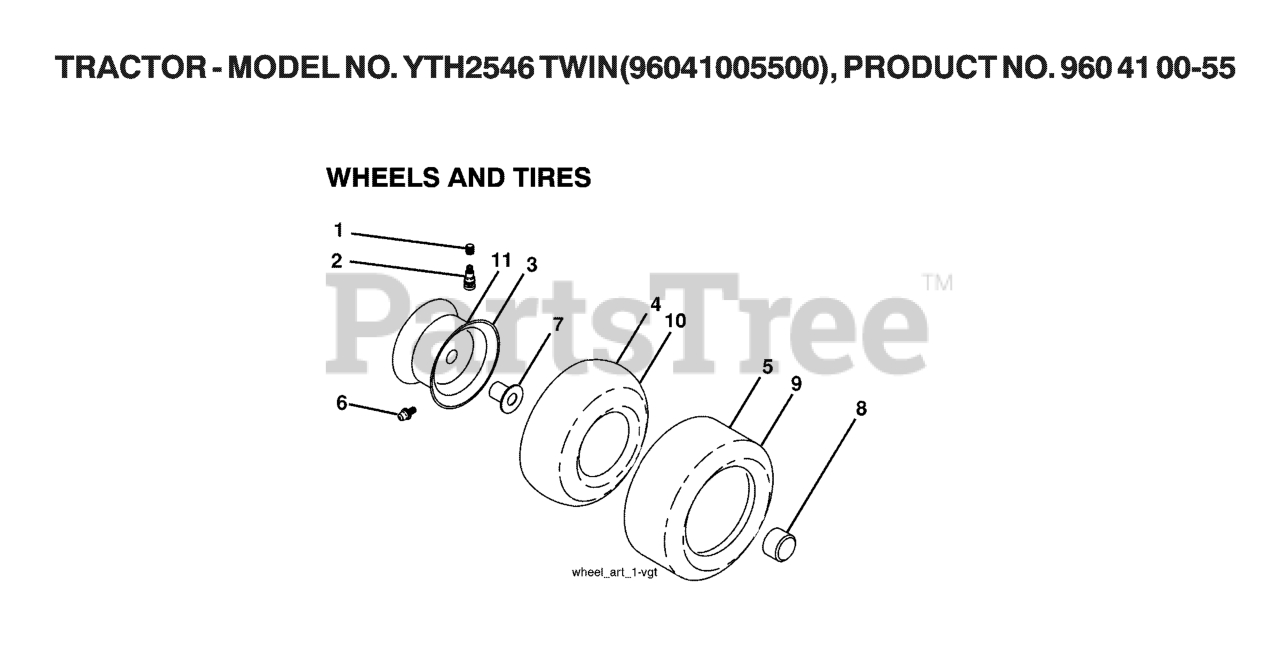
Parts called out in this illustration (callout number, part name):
2	VALVE STEM LT
3	RIM ASM 6" FRONT SILVER
4	TUBE.5.3/4.5/6
5	TIRE HEAVY DUTY
6	FITTING LT
7	BEARING T
8	CAP, AXLE BLK
9	TIRE.TS.20X10-8
10	TUBE
11	RIM ASM 8" REAR SILVER
